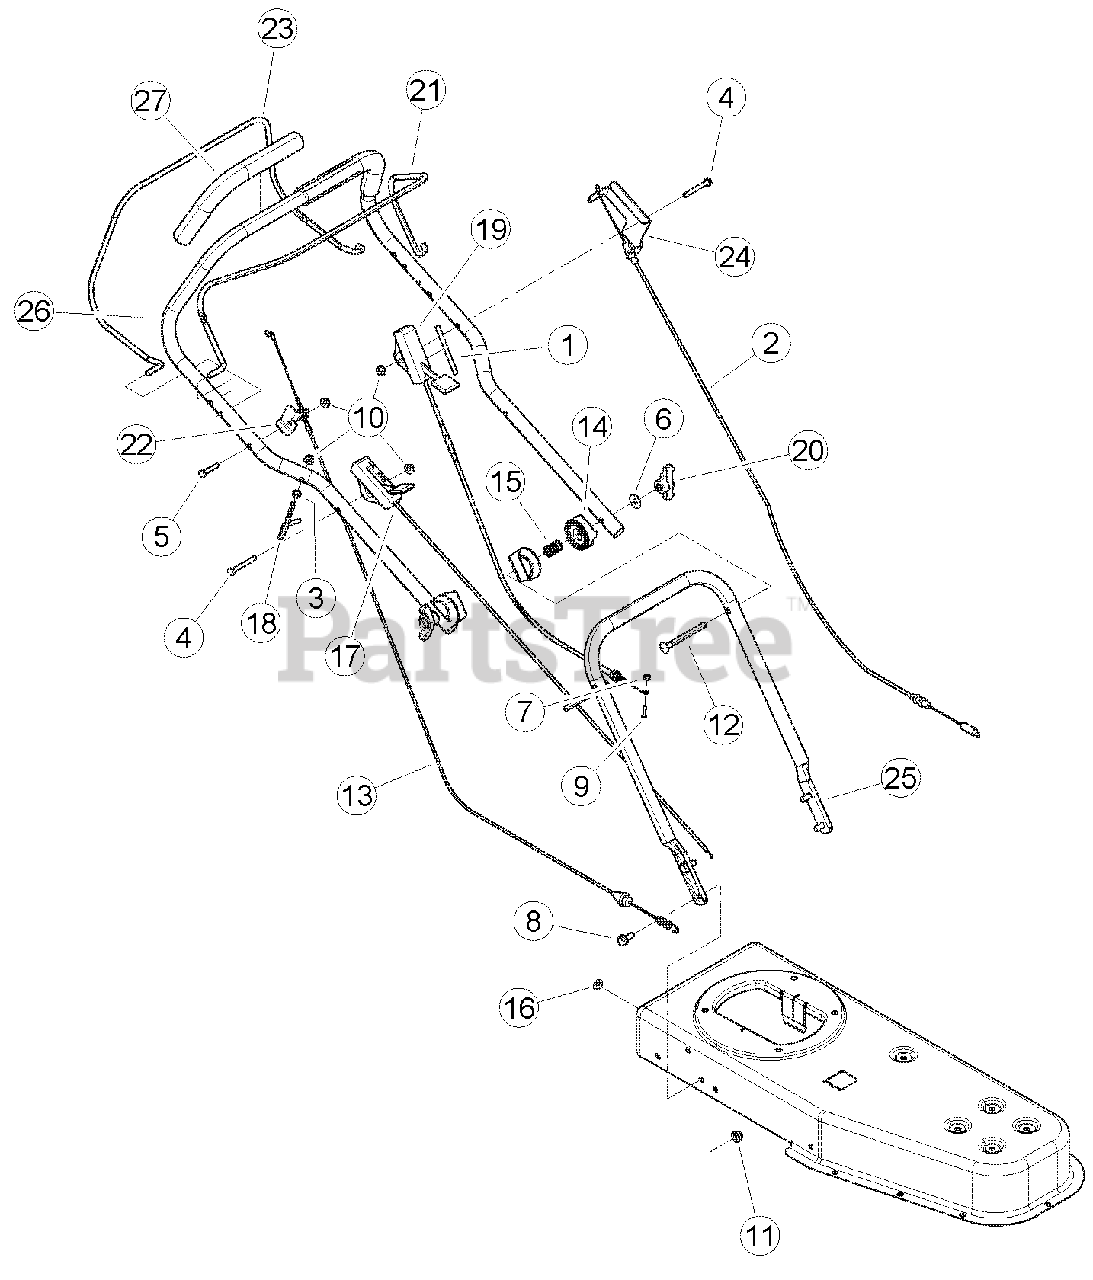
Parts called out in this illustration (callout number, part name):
1	DECAL, 3 SPEED
2	CABLE, SP CONTROL
3	NUT, 1/4 SERR FLANGE
4	BOLT, 1/4 X 2 HEX
5	BOLT, 1/4 X 1-1/4 HEX GR5 ZP
6	WASHER, 5/16 FLAT
7	NUT, #8 X 32 NYLOCK
8	BOLT, 5/16 X 3/4 SERR FLANGE UNC
9	SCREW, #8 X 32 X 3/4PAN PHP ZP
10	NUT, 1/4-20 NYLOCK FLANGE
11	NUT, 5/16-18 NYLOCK FLANGE
12	BOLT, 5/16-18 X 3-1/2 CRG LONG NECK GR5 ZP
13	CABLE, TRIMMER ENGAGEMENT
14	RETAINER, HANDLEBAR ADJUSTMENT
15	SPRING,RETAINER COMPRESSION
16	GROMMET, 3/8 ID X 5/8 OD
17	CONTROL, THROTTLE
18	GUIDE, RECOIL
19	CABLE, TRANSMISSION CONTROL
20	KNOB, 5/16-18 UNC TEE
21	BAIL, CONTROL
22	BRACKET, CABLE ANCHOR
23	BAIL, CONTROL
24	BRACKET, CABLE ANCHOR
25	SUPPORT, TRIMMER HANDLE
26	ASSEMBLY, TRIMMER HANDLE BAR, SERVICE PART
27	PAD, FOAM HANDLEBAR (32022-00)
